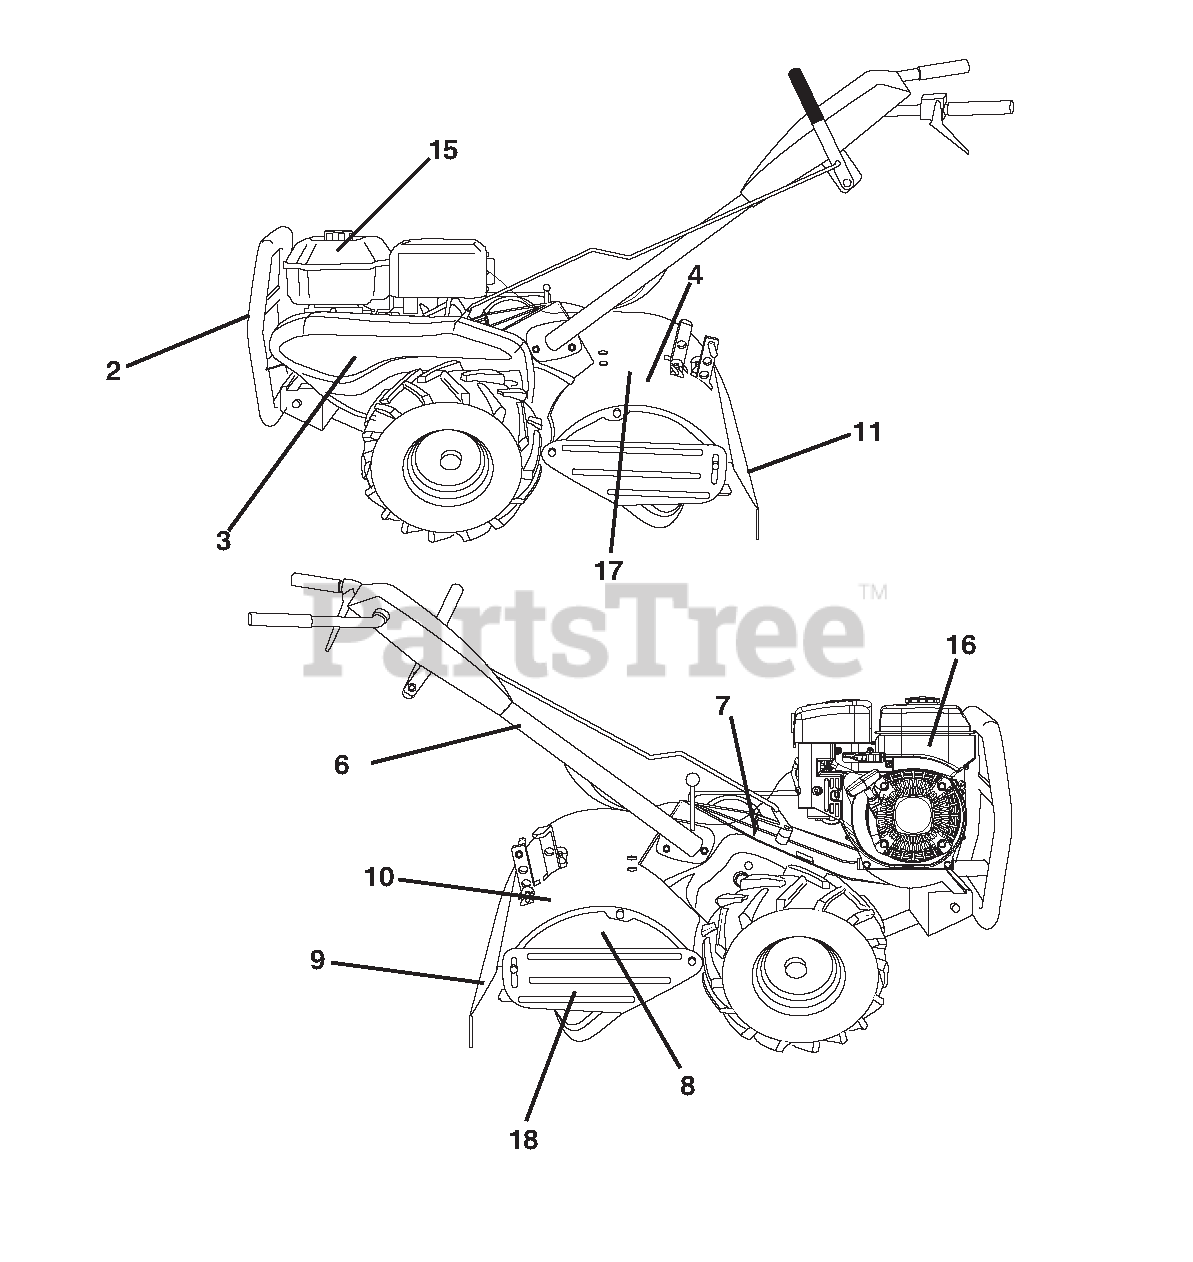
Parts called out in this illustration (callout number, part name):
2	DECAL, SUBARU TINE SHIELD
3	DECAL, BELT GUARD
4	DECAL, TINE SHIELD FORWARD
6	Decal, Hand Placement
7	Decal, Shift Indicator
8	Decal, Flag
9	Decal, Warning, DRT
10	DECAL, TINE SHIELD DRT REV
11	Decal Fender Service
15	DECAL, ETHANOL
16	Decal, Spark Arrester
17	DECAL, TOP DUAL
18	DECAL, SIDE
